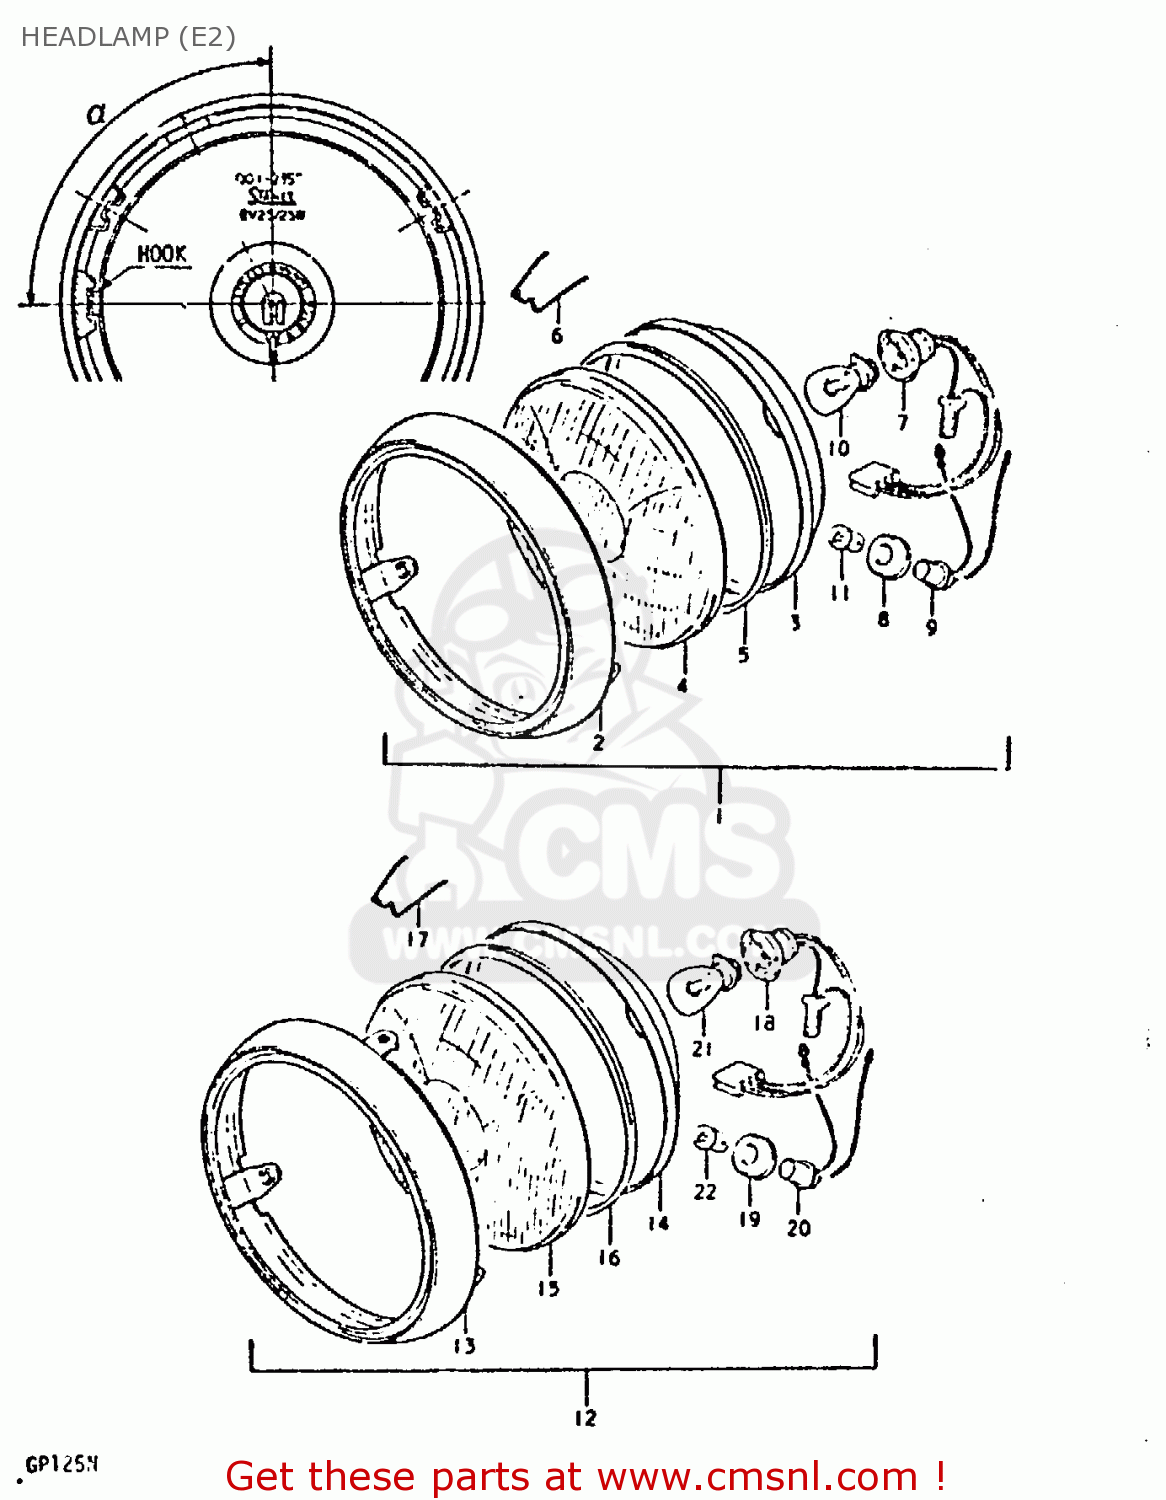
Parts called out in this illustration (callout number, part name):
1	HEADLAMP ASSY
2	RIM
3	REFLECTOR
4	LENS
5	GASKET (NAS)
6	SPRING
7	SOCKET
8	SEAL,PARKING BULB
9	SOCKET, PARKING LAMP
10	BULB
11	BULB(6V/3W)
